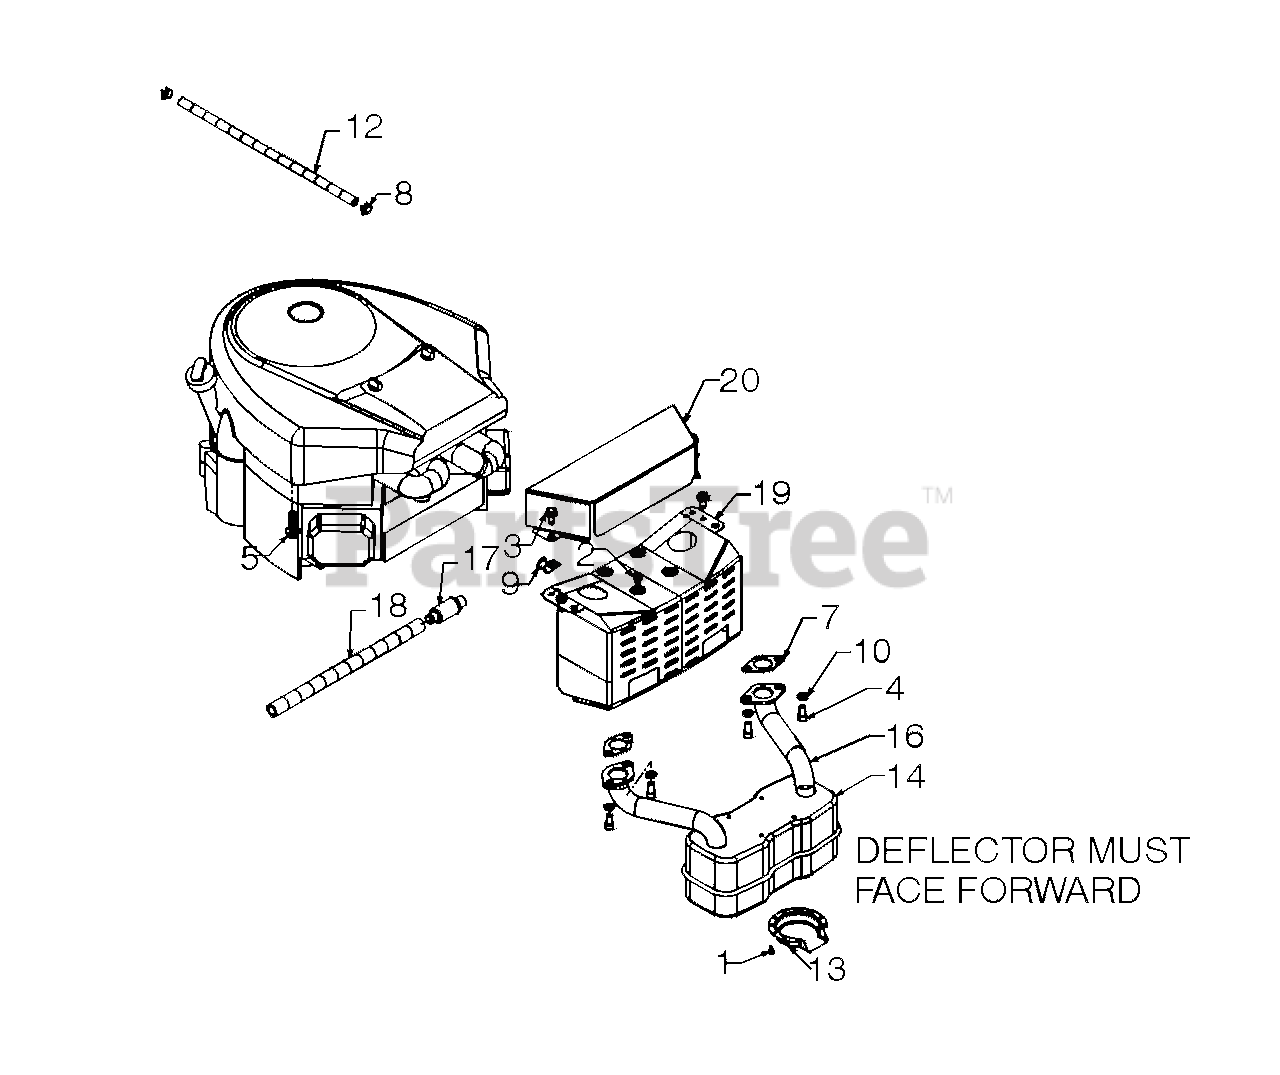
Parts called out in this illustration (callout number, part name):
1	Hex Tap Scr. #8-32 x .38" Lg.
2	Hex Washer TT-Tap Scr. 1/4-20 x 5" Lg.
3	Hex Washer TT-Tap Scr. 5/16-18 x .62"
4	Hex Washer TT-Tap Scr. 3/8-16 x 1.25"
5	Scr. 3/8-16 x 1.25 Lg.
7	Exhaust Gasket
10	Lock Washer 5/16 Reg.
12	Hose, Fuel Line
13	Dfl, Muffler
14	Muffler, Twin Inlet
16	Exhaust Tube-L.H.
17	Oil Drain
18	Oil Drain Hose - 12"
20	Heat Shield
